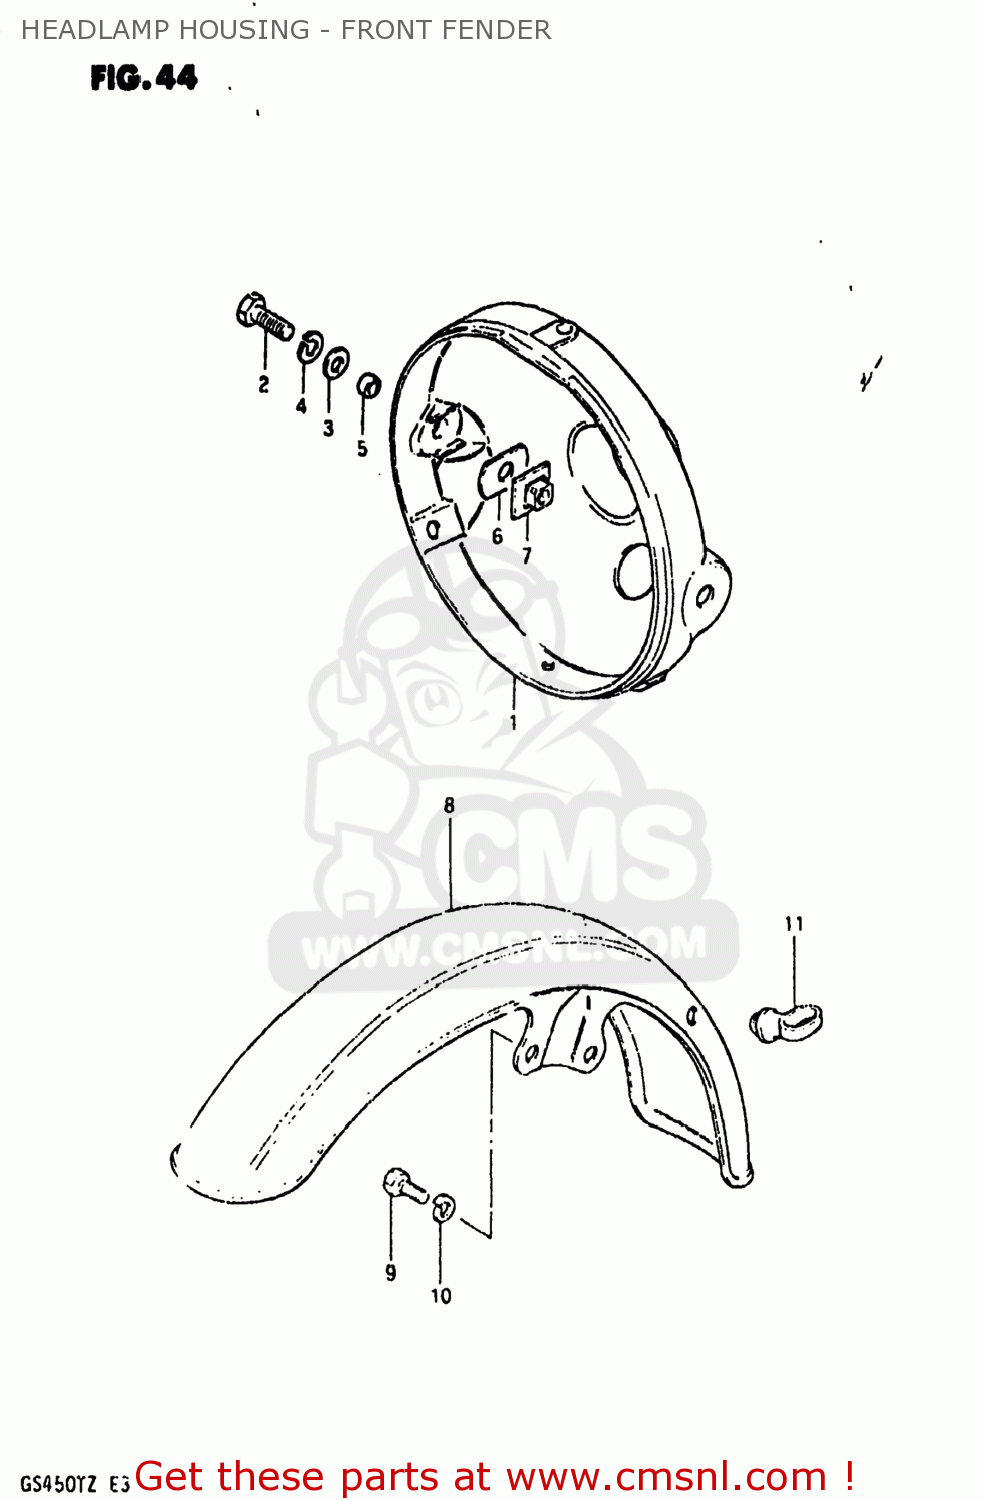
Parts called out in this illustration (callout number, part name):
1	HOUSING,HEADLAMP
2	BOLT
3	WASHER
4	LOCK WASHER
5	SPACER (8.8X12X7)
6	CUSHION
7	PLATE,HEADLAMP HOUSING
8	FENDER,FR
9	BOLT
10	LOCK WASHER
11	GUIDE,CABLE
